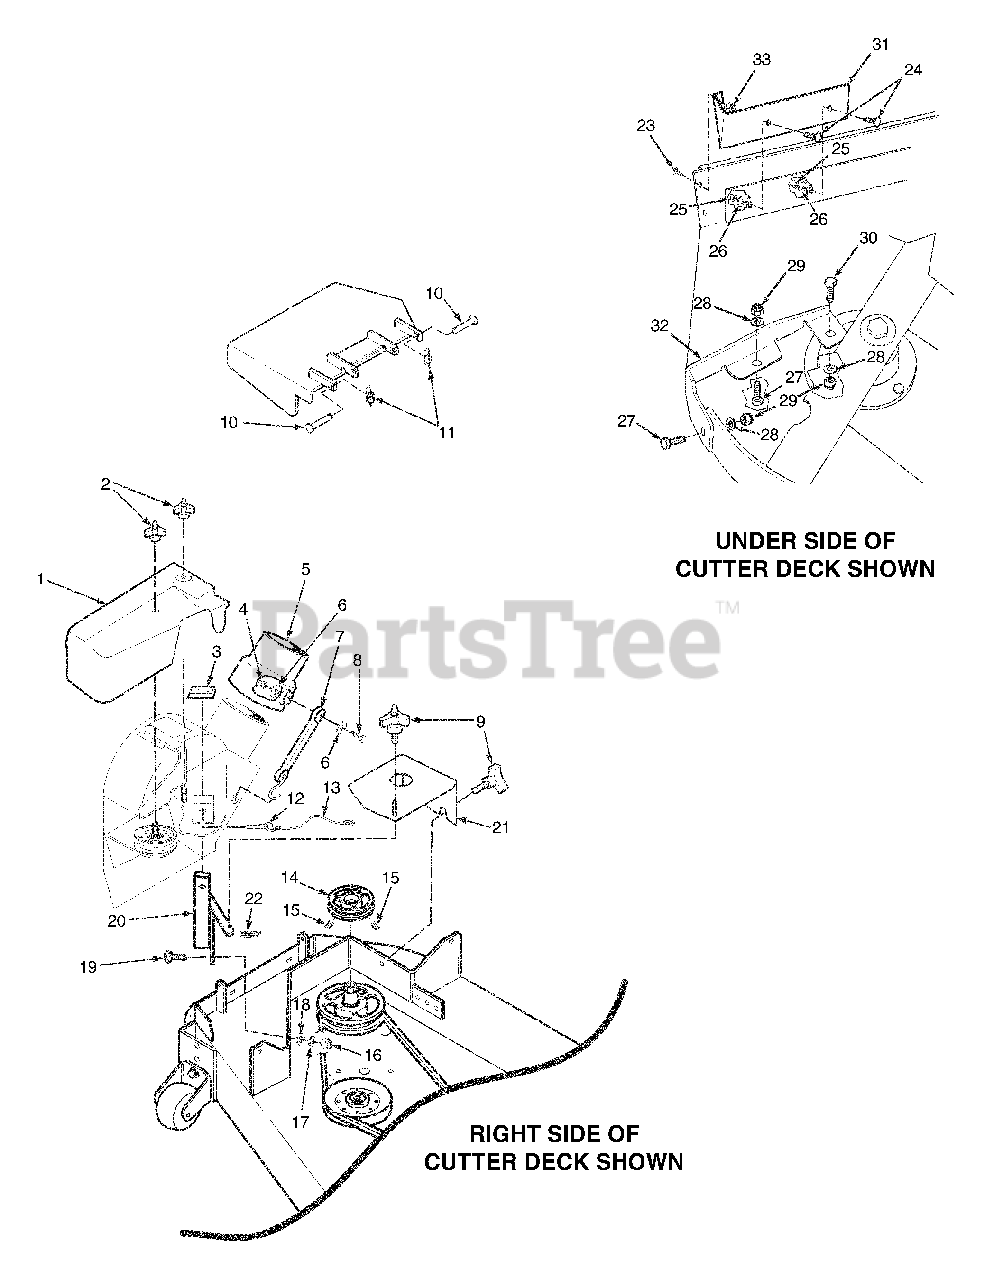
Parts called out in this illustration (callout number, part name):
1	Belt Cover, GC-STC
2	Wingnut, Plastic 3/8 Small
3	Cap, Square Vinyl
4	Nut, Elastic Stop 1/4-20
5	Adapter, Blower GC-STC,
6	Flatwasher, 1/4-.312 x .750 x .065
7	Rubber Strap 7-3/4"
8	Bolt, Hex Head 1/4-20 x 1-1/4"
9	Knob W/Stud, 3/8-16 x 1-1/4"
10	Clevis Pin, 5/16 x 1-1/2"
11	Pin, Rue Cotter 5/16 Dia.
12	Pin, Ring 1/2 x 2-1/4"
13	Lanyard
14	Pulley, 3-3/4" for 48" Deck
15	Setscrew, 5/16-18 x 3/8"
16	Nut, Elastic Stop 3/8-16
17	Lockwasher, 3/8"
18	Flatwasher, 3/8-.391 x .938 x .105
19	Bolt, Carr. 3/8-16 x 1-1/4" Grade 5
20	Mounting Post Weldment, Blower
21	Belt Cover
23	Bolt, Hex Head 1/4-20 x 3/4"
24	Bolt, Carriage 3/8-16 x 1"
25	Nut, Elastic Stop 3/8-16
26	Flatwasher, 3/8-.391 x .938 x .105
27	Bolt, Hex Head 5/16-18 x 1"
28	Flatwasher, 5/16-.375 x .875 x .083
29	Nut, Elastic Stop 5/16-18
30	Bolt, Hex Head 5/16-18 x 1-3/4"
31	Baffle, 48"
32	Baffle, 48" Deck
33	Nut, Serrated Flange 1/4-20
